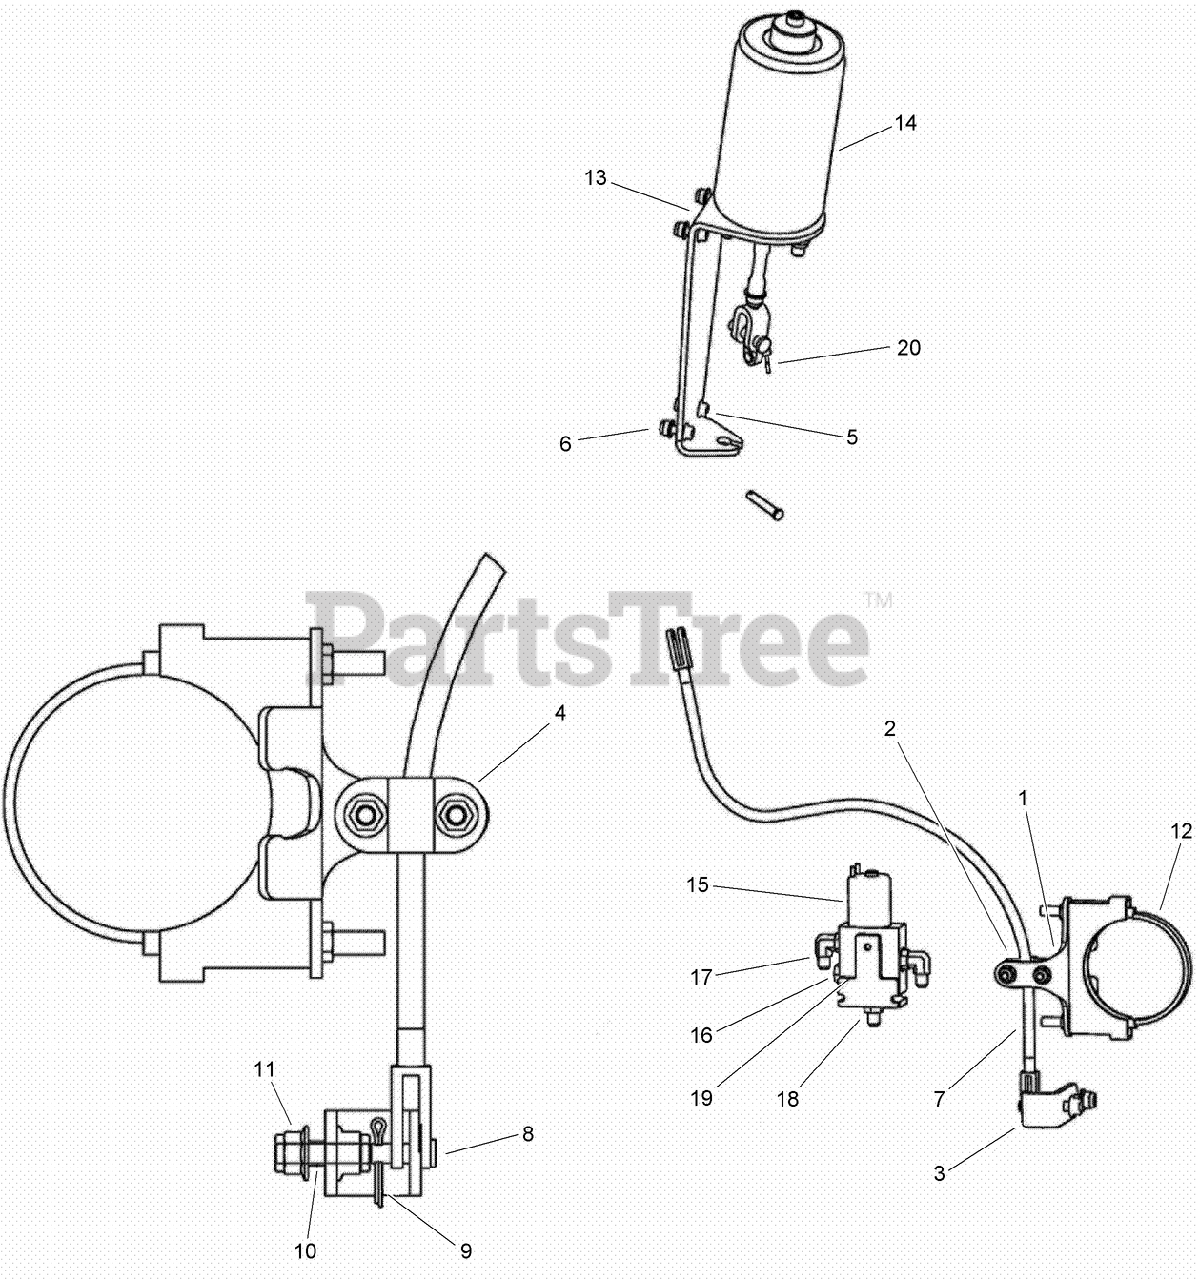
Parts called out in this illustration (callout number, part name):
1	BRACKET-Parking Brake Cable
3	PLATE-Parking Brake Mount
4	CLAMP-Cable
5	SCREW-HH
6	NUT-TORQUE, PREVAILING
7	BRAKE CABLE ASM
8	PIN-CLEVIS
9	PIN-COTTER
10	SCREW-FLANGE
11	NUT-FLANGE, NYLOCK
12	CLAMP-4 Muffler
13	MOUNT-Parking Brake
14	HYD CYLINDER RELEASE ASM
15	SOLENOID VALVE ASM
16	PLUG-Hex Hd, ORB 3/8
17	ELBOW-90 DEG (ADJUSTABLE 37 DEG)
18	CONNECTOR-Str Thd 3/8, 37FL-ORB 3/8
19	PLATE-Spacer
20	LINK-CABLE, PARKING BRAKE
